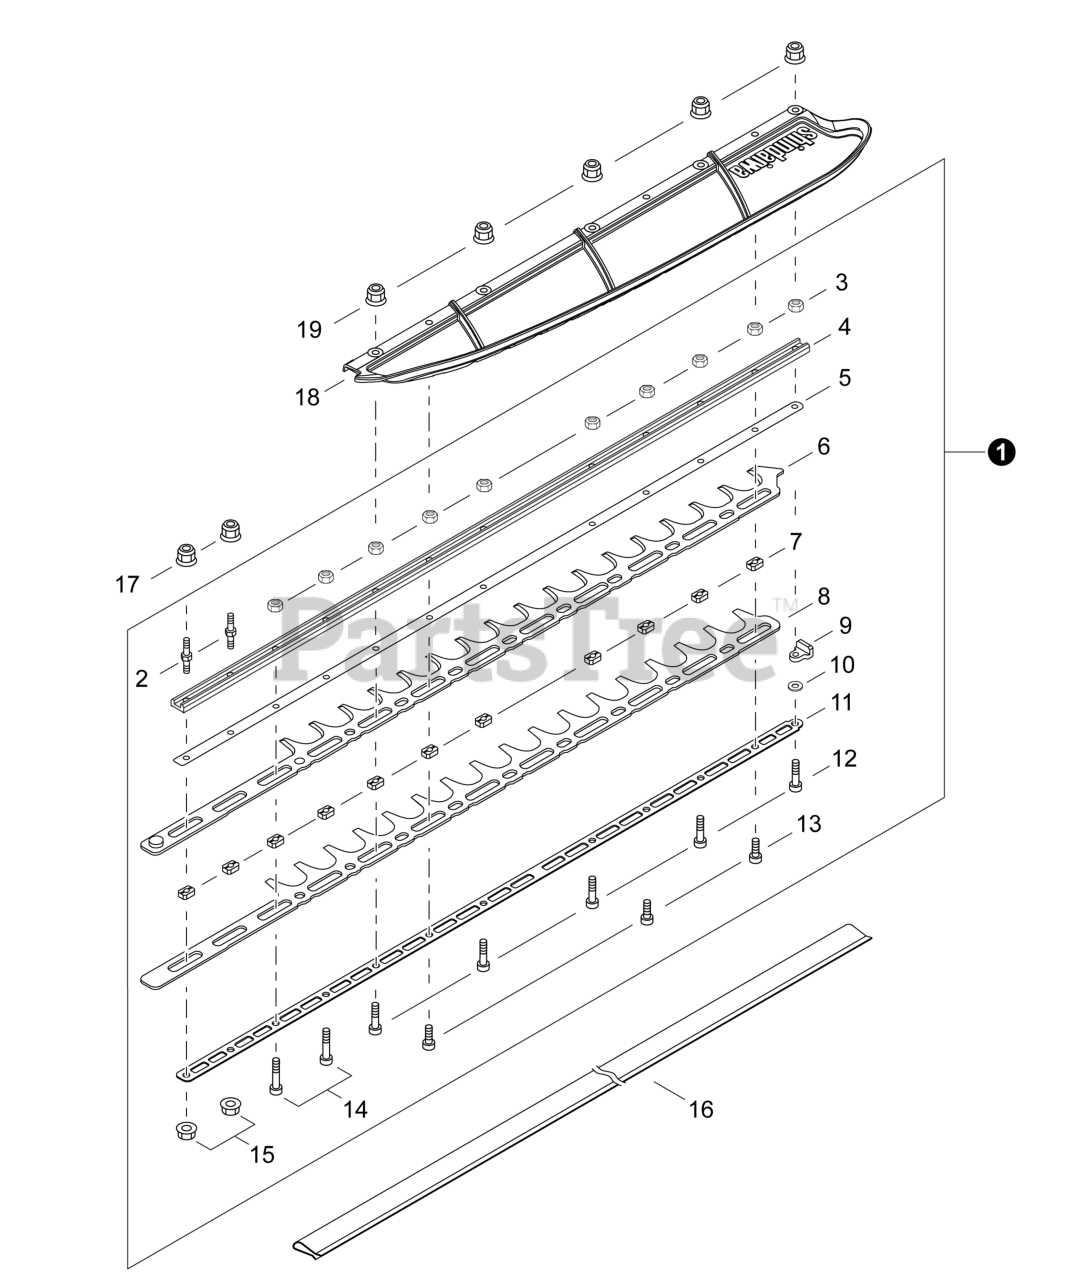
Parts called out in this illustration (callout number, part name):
1	CUTTER ASSY, 28"
2	STUD, MOUNTING M5x36
4	SUPPORT, BLADE 28"
5	SUPPORT, BLADE 28"
6	CUTTER 28"
8	CUTTER 28"
11	SUPPORT, BLADE 28"
12	BOLT, TORX 5x25
13	BOLT, TORX 5x16
14	BOLT, TORX 5x30
15	NUT, FLANGE M5
16	SCABBARD
17	NUT, FLANGE M5
18	DEFLECTOR, DEBRIS
19	NUT, FLANGE M5
